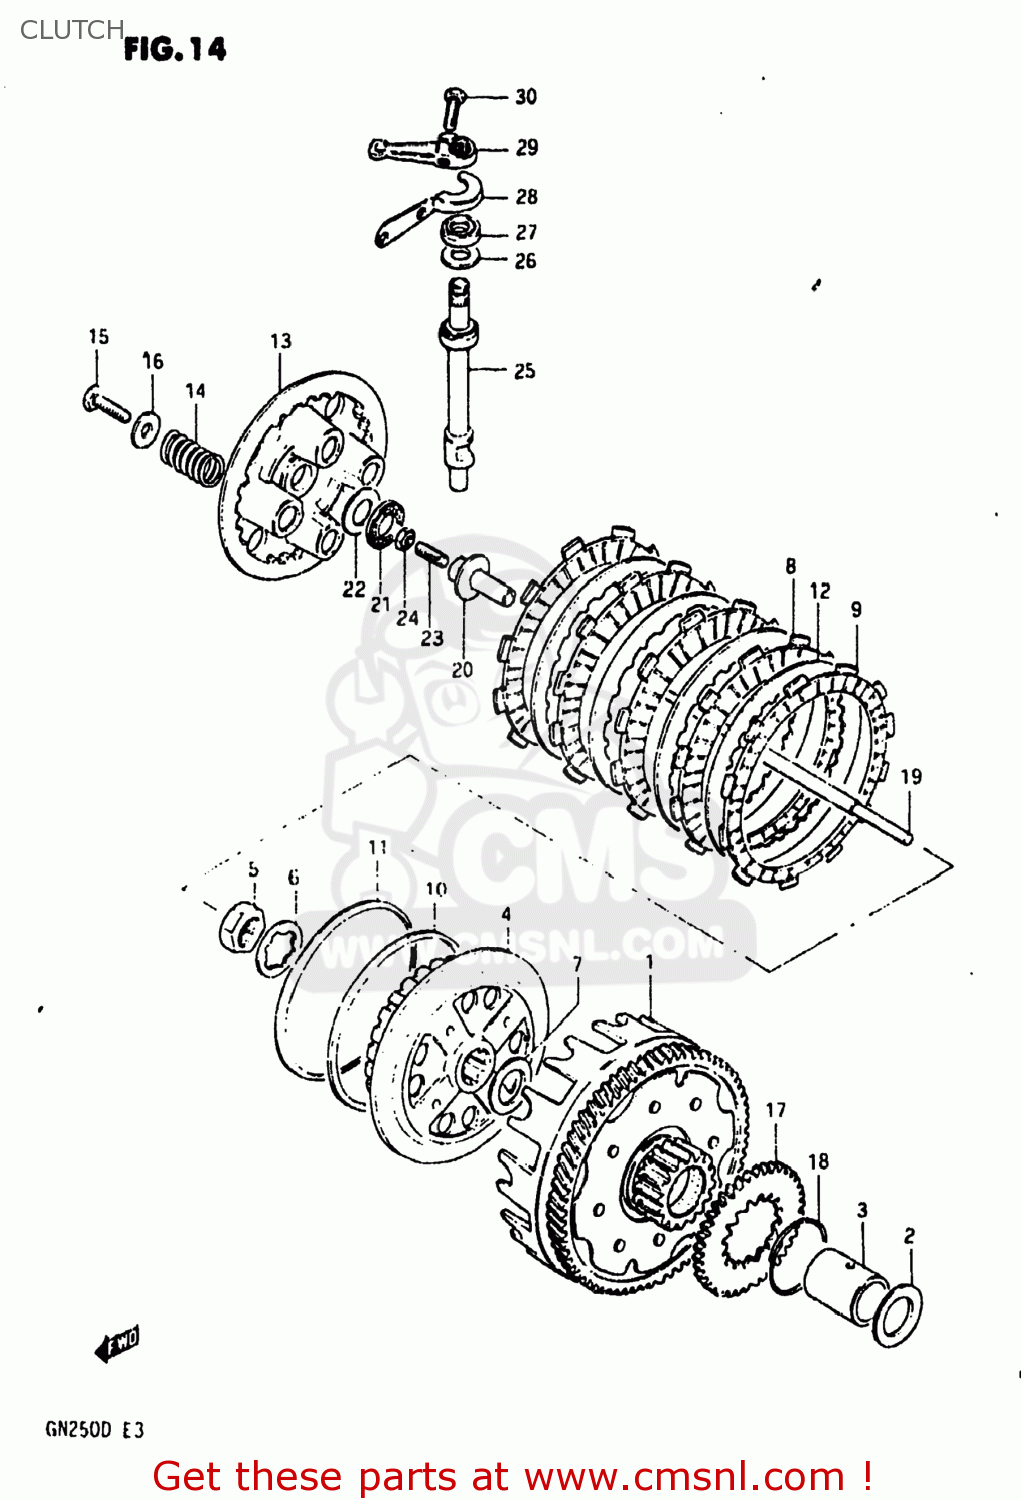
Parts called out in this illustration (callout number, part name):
1	GEAR ASSEMBLY,PRIMARY DRIVE
2	WASHER
3	SPACER(22X28X37.5)
4	HUB,CLUTCH SLEEVE
5	NUT
6	WASHER,LOCK
7	WASHER
8	PLATE,CLUTCH DRIVE (MCA)
9	PLATE,CLUTCH DRIVE
10	SEAT,WAVE WASHER(T:1.4)
11	WASHER
12	PLATE,CLUTCH DRIVEN
13	DISC,CLUTCH PRESSURE
14	SPRING
15	BOLT, UPPER
16	WASHER
17	GEAR,OIL PUMP DRIVE
18	CIRCLIP
19	ROD,CLUTCH PUSH
20	PIECE,CLUTCH PUSH
21	BEARING(15X28X2)
22	WASHER
23	SCREW
24	NUT 6MM
25	CAMSHAFT,CLUTCH RELEASE
26	WASHER (14.2X22X1)
27	OIL SEAL
28	PLATE,CLUTCH RRS CAMSHAFT SEAL
29	ARM,CLUTCH RELEASE
30	BOLT
